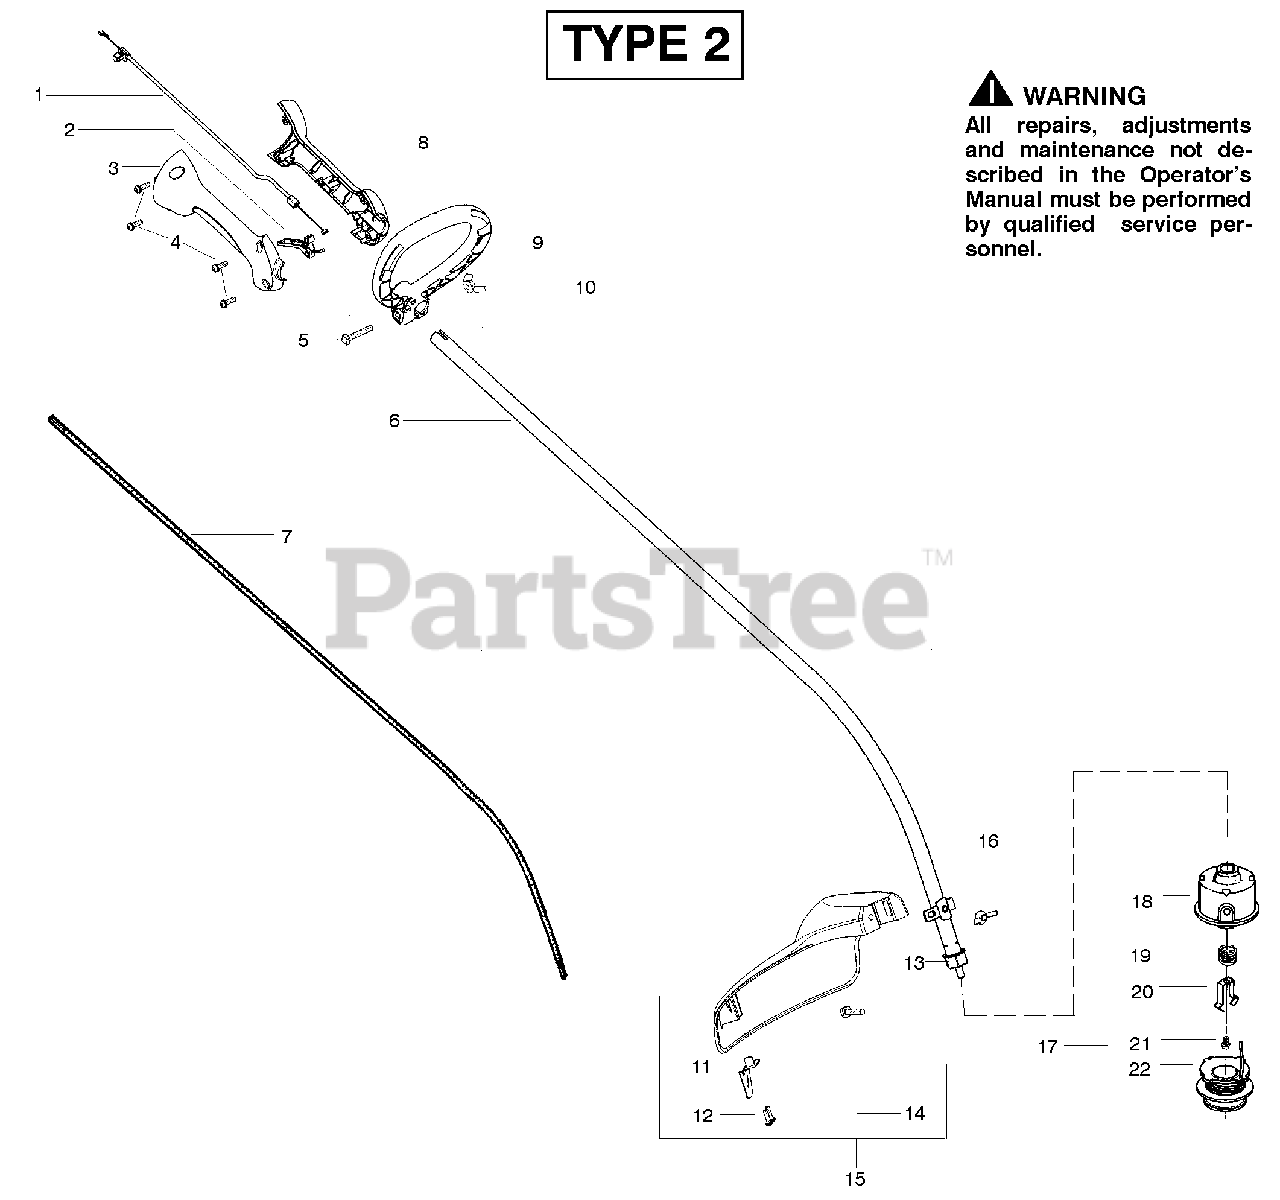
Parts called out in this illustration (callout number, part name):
1	Assy-Throttle Cable
3	Throttle Hsg. (Right)
4	Screw-Throttle Hsg.
6	Assy-Drive Shaft Hsg.
7	Shaft- Flex
8	Throttle Hsg. (Left)
9	Assy-Handle
10	Wingnut
11	Kit - Line Limiter
12	Screw-Line Limiter
13	Dust Cup
15	Kit-Shield Assy
16	Wingnut
17	Accy-TNG IV Cutting Head
18	Assy-Hub
19	Spring-Compression
20	Clip-Retainer-Head
22	Accy- Spool w/Line
